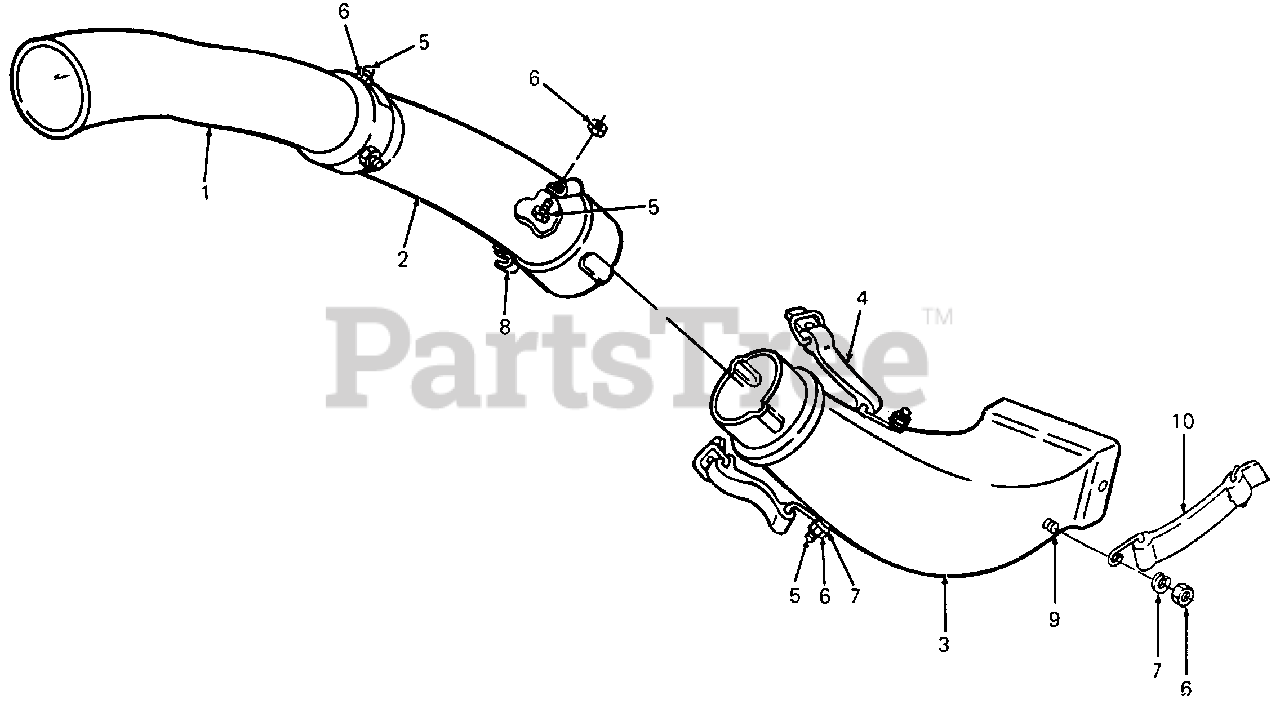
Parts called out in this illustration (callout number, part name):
1	Elbow, Catcher
2	Tube, Catcher
3	Discharge Chute
4	Strap Assy, Retainer
5	Screw, Hex, 1/4-20 X .50 Lg
6	Nut, Hex Insert Lock, 1/4-20
7	Washer, Spring, .265 ID X .562 OD
8	Hook Bracket, Retainer
9	Screw, Hex Cap, 1/4-20 X .62 Lg
10	Strap Assy, Chute Retainer
